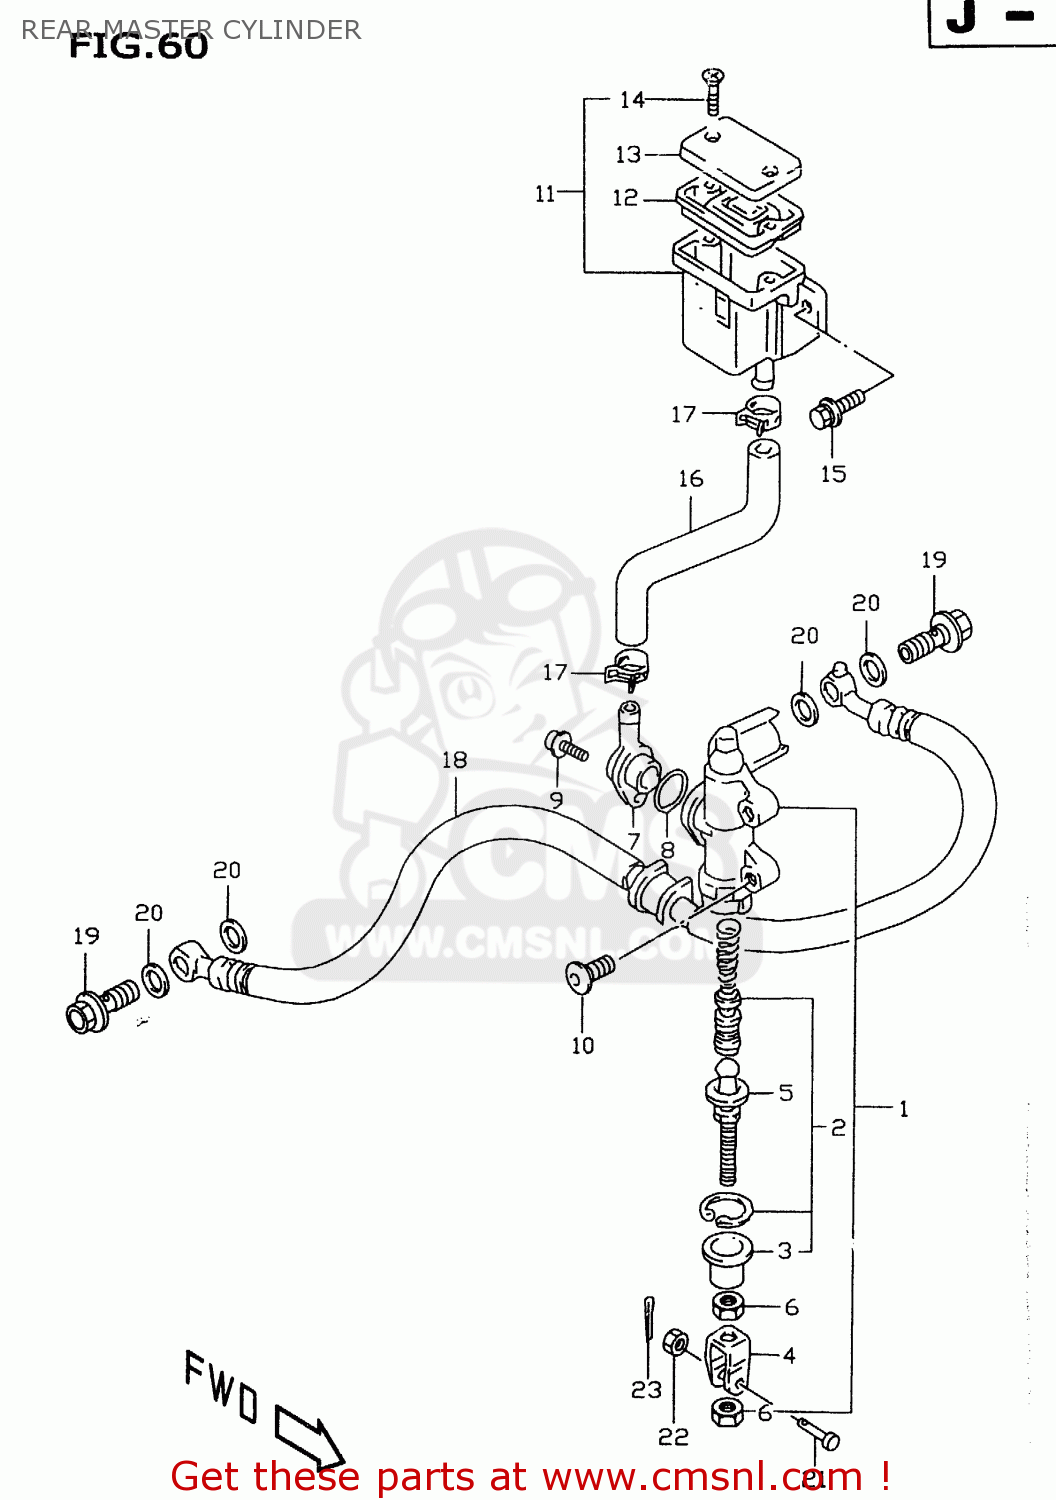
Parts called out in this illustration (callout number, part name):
1	CYLINDER ASSY,RR MASTER
2	PISTON/CUP SET
3	BOOT
4	YOKE
5	ROD,PUSH
6	NUT
7	CONNECTOR
8	O RING
9	SCREW
10	SCREW(6X20)
11	TANK ASSY,RESERVOIR
12	DIAPHRAGM
13	CAP
14	SCREW
15	BOLT
16	HOSE,RESERVOIR TANK
17	CLIP
18	HOSE,RR BRAKE
19	BOLT UNION
20	WASHER(10X15X1.5)
21	PIN
22	WASHER
23	PIN
